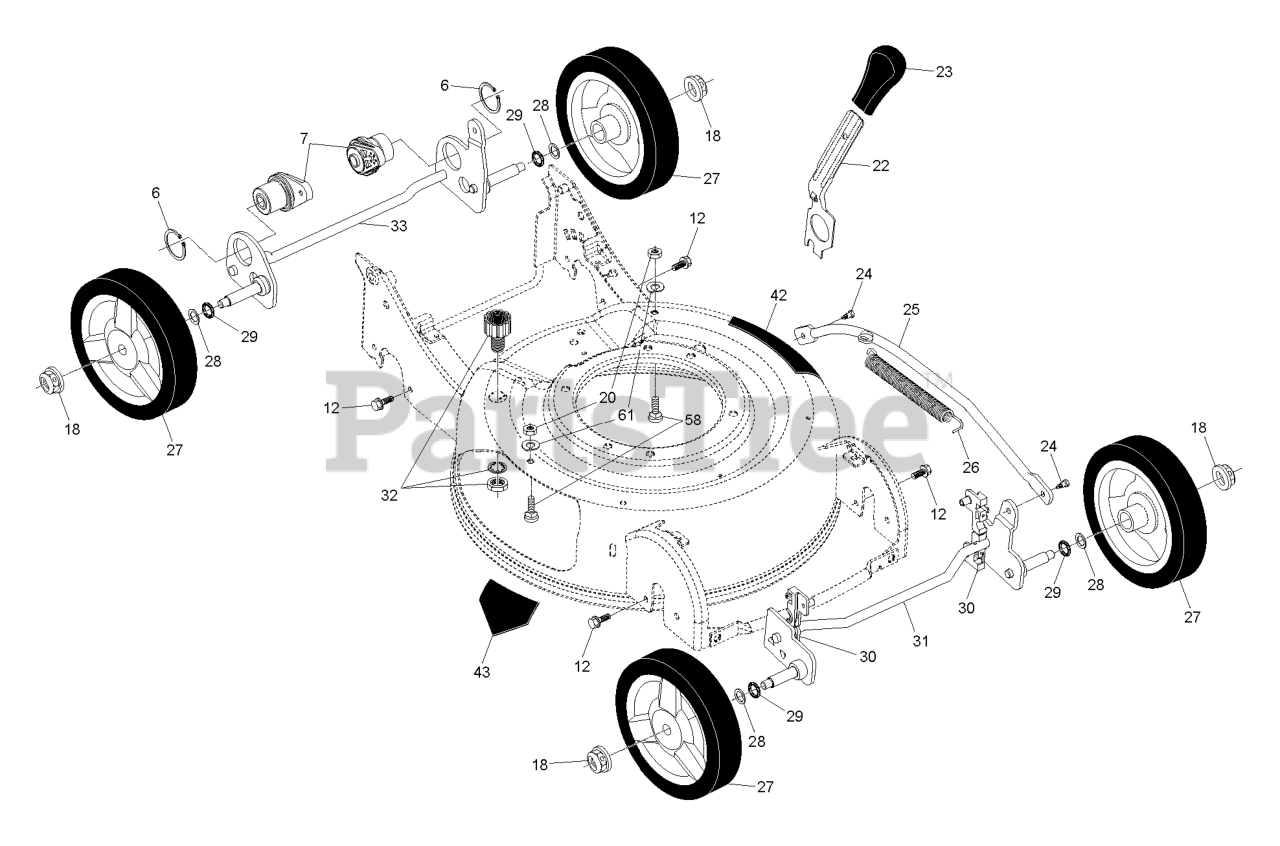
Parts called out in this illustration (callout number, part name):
6	RETAINING RING (2 2)(3 2)
18	NUT.HEX.FLANGE.3/8-16.LO(3 2)
20	NUT, HEX
24	SHOULDER BOLT SEMI GIMLET PT.
26	SPRING EXTENSION
27	WHEEL & TIRES ASSY, FRONT
28	WASHER.FLAT.1/2
29	O-RING..070X.487.NEOPRENE
30	BUSHING.FRONT.TORQUE.S
33	AXLE.ASM.REAR.TORQUE.BZP
43	DECAL.INTERNATIONL.CUTFINGER
58	BOLT.CARRIAGE.1/4-20 X 7/8
61	LOCKWASHER
